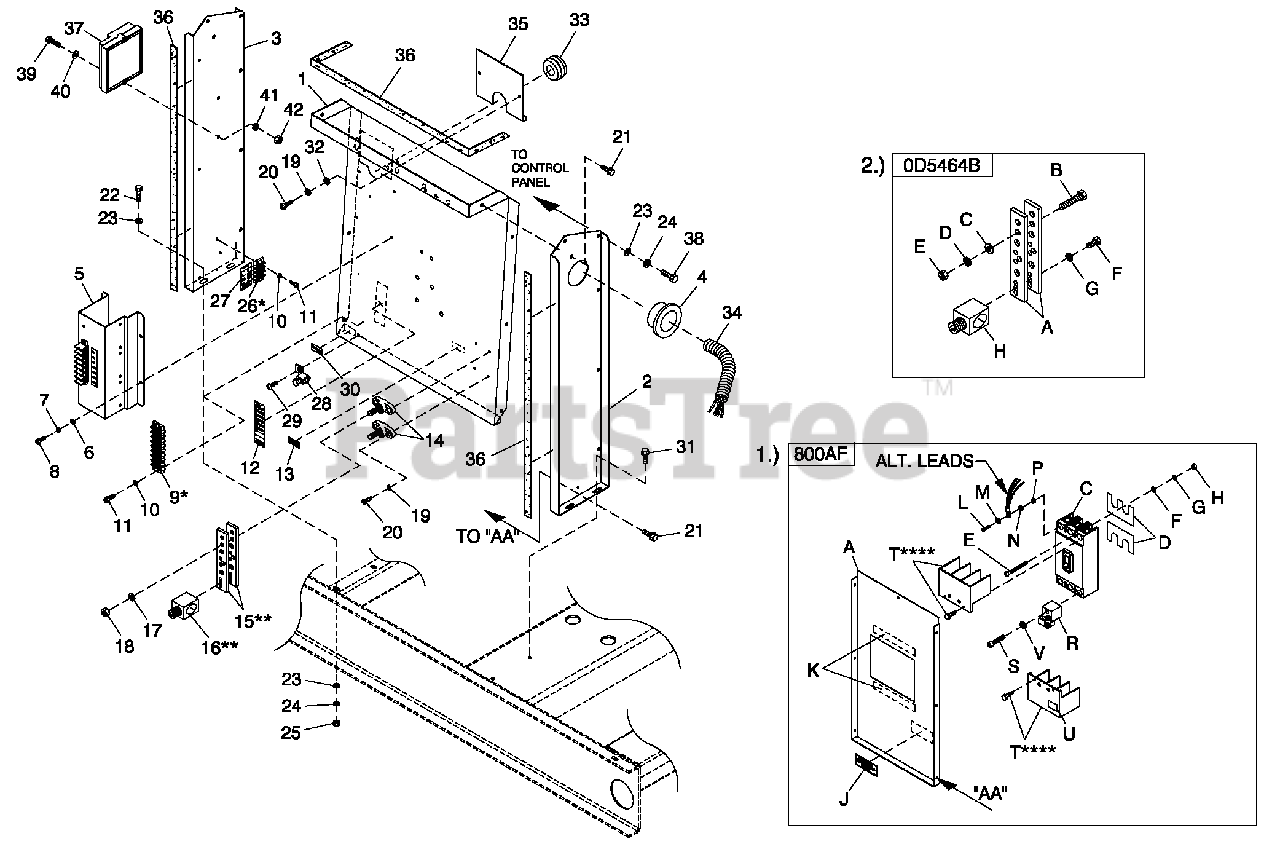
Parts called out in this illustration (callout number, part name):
0G0171A	STAND RH CONTROL CPL C5 2 HOLE
1	PANEL CB CONN BOX
2	STAND RH CONTROL CPL C5
3	STAND LH CONTROL CPL C5
4	BUSHING SNAP SB-2.5-31
5	A SSY PCB INTERFACE 1PH 240V
6	WASHER FLAT M4
7	WASHER LOCK #8-M4
8	SCREW PHTT M4-0.7 X 10 ZYC
9	BLOCK TERM 2 0 A 8 X 6 X 1100V
10	WASHER LOCK #6
11	SCREW PHTT #6-32X1/2 ZYC
12	DECAL CPL CUST CONN H CTRL
13	DECAL NEUTRAL
14	JUNCTION BLOCK 3/8-16
15	BUS BAR NEUTRAL BLOCK 390
16	LUG SLD LSS 600/250-1/0 X 1/4-28
17	WASHER LOCK 3/8
18	NUT HEX 3/8-16 STEEL
19	WASHER LOCK M5
20	SCREW PHTT M5-0.8X 16 ZYC
21	SCREW THF M6-1 X 16 N WA Z/JS
22	SCREW HHCM6-1.0X 20 G8.8
23	WASHER FLAT 1/4-M6 ZINC
24	WASHER LOCK M6-1/4
25	NUT HEX M 6 X 1.0 G 8YEL CHR
26	BLOCK TERM 2 0 A 6 X 3 X 1100V
27	DECAL CUST CONN 120V UTILITY
28	LUG SLD LSS #6-14X 13/64CU
29	SCREW HHTT #10-32X3/8 CZ
30	DECAL GROUND LUG
31	SCREW HHTT M6-1.0X16ZYC
32	WASHER FLAT M5
33	GROMMET 1.25 X .25 X .75
34	CONDUIT FLEX 2.0" ID
35	PLATE WIRE SNGLGALV
36	TAPE ELEC 1/2 FOAM (AS REQ'D)
37	A SSY PCB HSB CTRL IGN MODULE
38	SCREW HHC M6-1.0X 16G8.8
39	SCREW PPHM #10/32X2
40	WASHER FLAT #10 ZINC
41	WASHER LOCK #10
42	NUT HEX #10-32 STEEL
A	COVER, CB 803 C5
C	CIRCUIT BREAKERS 800A FRAME
D	INSULCB800AF
E	SCREW RHM 1/4-20X1-1/2
F	WASHER FLAT 1/4-M6 ZINC
G	WASHER LOCK M6-1/4
H	NUT HEX 1/4-20 STEEL
J	DECAL CUSTOMER CONNECT INSIDE
K	TAPE ELEC 1/2 FOAM
L	SCREW SHC M 10-1.50 X 40 G12.9
M	WASHER FLAT 3/8-M10 ZINC
N	WASHER LOCK 3/8
P	NUT HEX M10-1.5G8YEL CHR
R	LUG SLD LSS 3/0-400X3 MCM AL/CU
S	SCREW SHC M6-1.0X 50 G8.8
T	TERM. COVER VITZROTECH 400AF CB
U	DECAL TERMINAL SHOCK HZD BI
V	WASHER LOCK M6-1/4
A	BUS BAR NEUTRAL BLOCK 390
B	SCREW HHC M8-1.25 X 45 G8.8 FT
C	WASHER FLAT 5/16-M8 ZINC
D	WASHER LOCK M8-5/16
E	NUT HEX M8-1.25G8YEL CHR
F	SCREW HHC 1/4-28 X 3/4 G5
G	WASHER LOCK 1/4-M6SS
H	LUG SLD LSS 600/250-1/0 X 1/4-28
